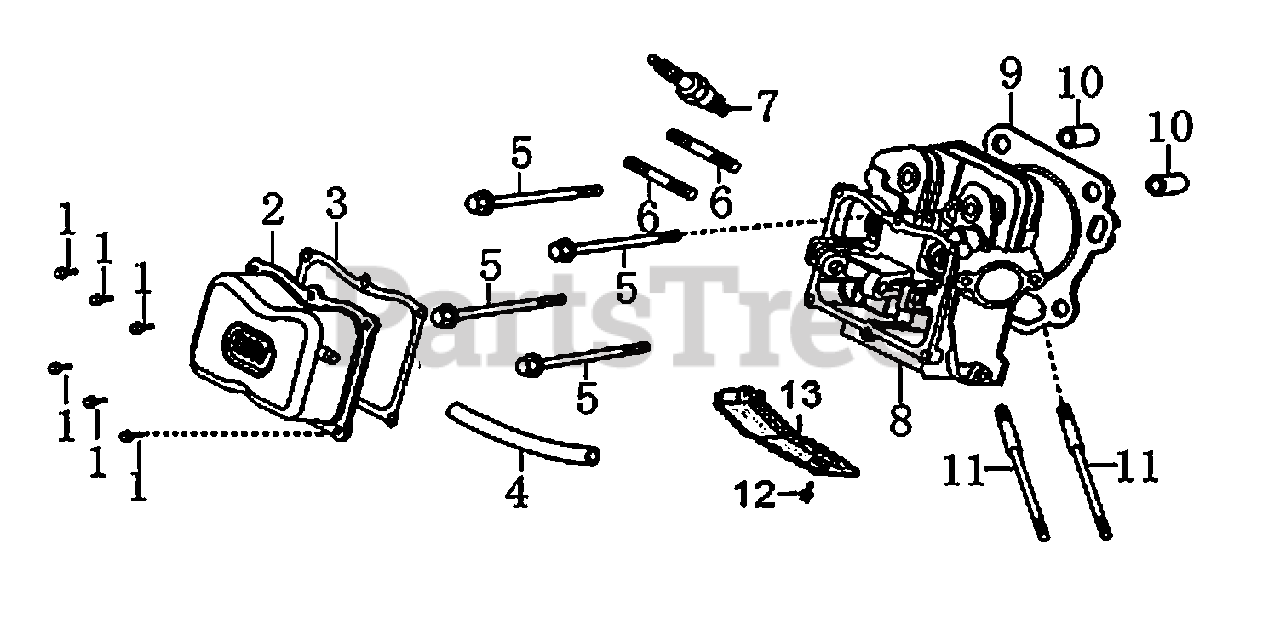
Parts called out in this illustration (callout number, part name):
1	BOLT, FLANGE
2	COVER COMP. HEAD
3	PACKING, HEAD COVER
4	TUBE, BREATHER
5	BOLT, FLANGE, 10×80
6	BOLT, STUD, EXHAUST
7	SPARK PLUG
8	CYLINDER HEAD COMP
9	GASKET, CYLINDER
10	PIN, DOWEL
11	BOLT, STUD, INTAKE
12	BOLT, FLANGE M6×12
